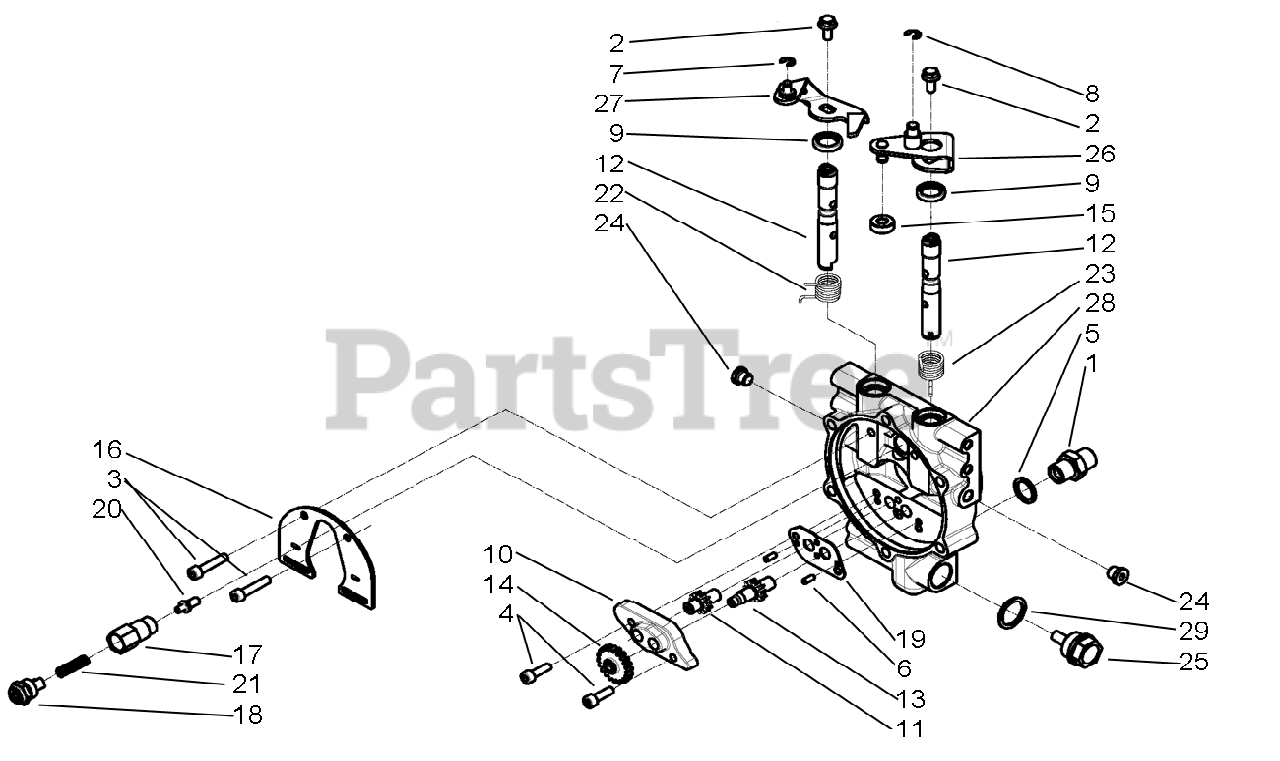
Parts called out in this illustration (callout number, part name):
1	NIPPLE M+M 3/8
2	CAP SCREW
3	SCREW TCEI M6X30
4	SCREW TCEI M6X20
5	COPPER WASHER 16,7X22/1,5
6	CYLINDRICAL PLUG
7	SEEGER RING
8	SEEGER RING E 6
9	OIL SEAL
10	COVER
11	DRIVEN GEAR
12	DISTRIBUTOR
14	PUMP GEAR
15	ROLLER
16	SHIELD
17	VALVE SEAT
19	COUNTERWEIGHT
20	VALVE
21	SPRING
22	SPRING
23	SPRING
26	CLUTCH LEVER
27	LEVER
28	CLUTCH FLANGE
29	GASKET 22X28X1,5 CU 99,5
